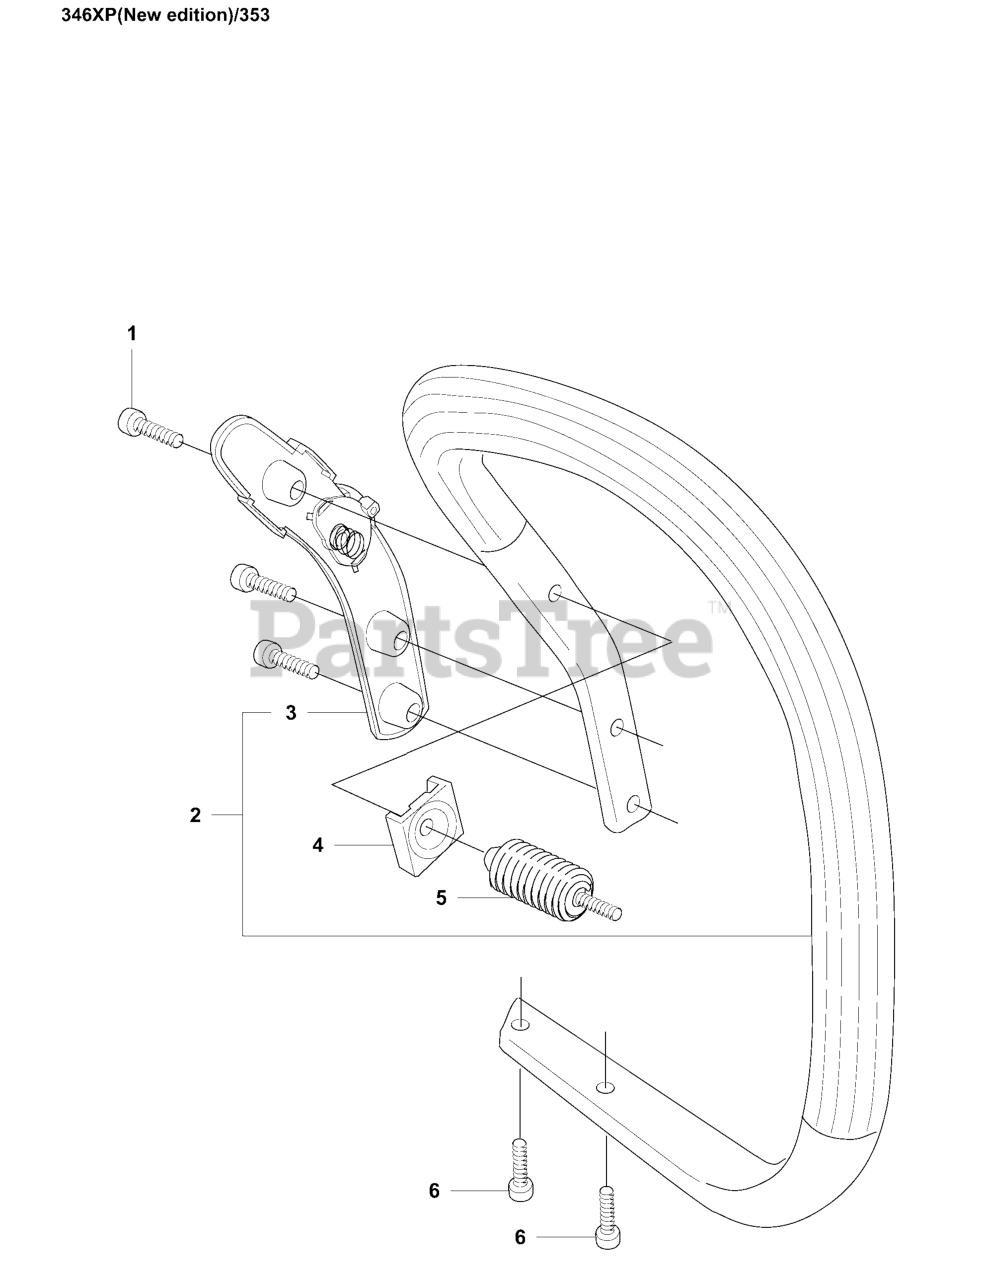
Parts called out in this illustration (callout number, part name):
2	FRONT HANDLE
3	SWITCH
6	SCREW IHSCFT
